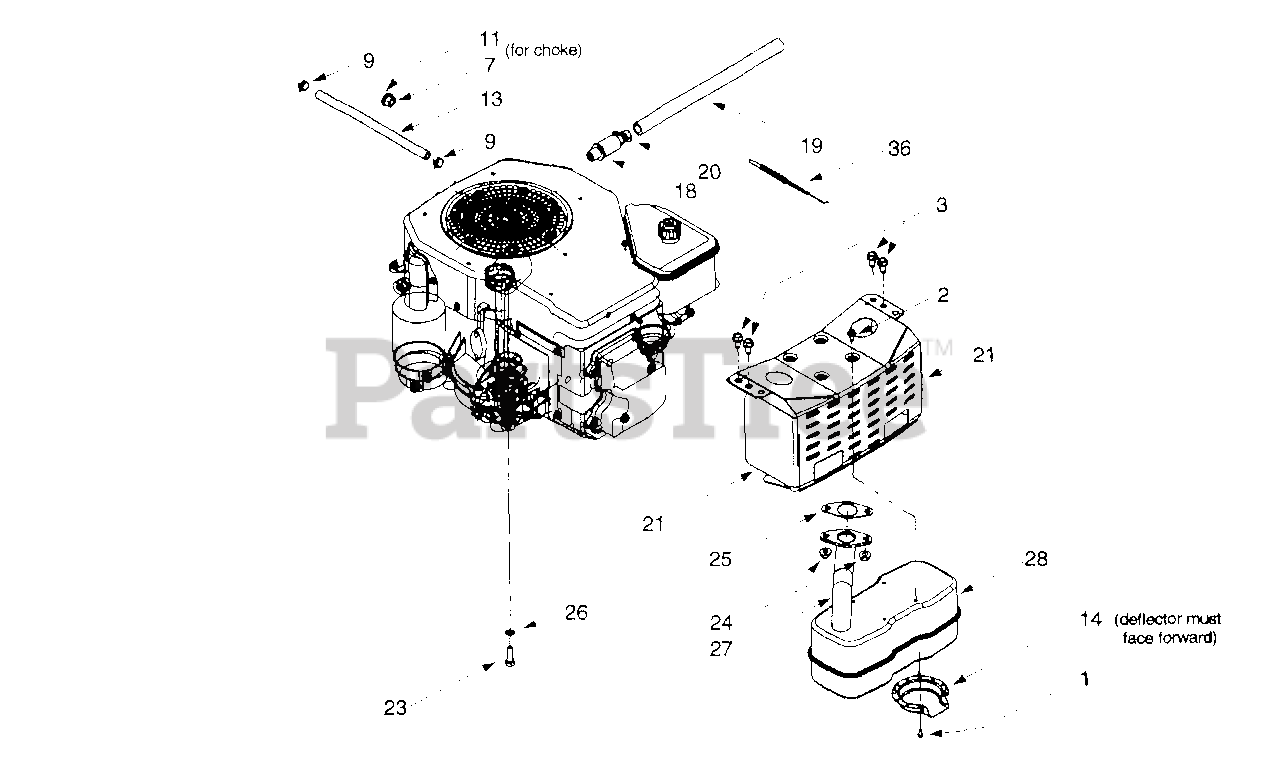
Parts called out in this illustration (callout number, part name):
1	Self Tapping Screw, #8-32 x .375
2	Self Tapping Screw, 1/4-20 x .5
3	Self Tapping Screw, 5/16-18 x .625
7	Hex Nut, 3/8-16
9	Hose Clamp
11	Flat Washer, 3/8 x .56 x .018
13	Fuel Line Hose
14	Muffler Deflector
18	Oil Drain Valve
19	Oil Drain Hose
20	Oil Drain Cap
23	Hex Cap Screw, M8-1.25 x 25
24	Flange Nut, M8-1.25
25	Exhaust Gasket
26	External Lock Washer, 5/16
27	Exhaust Pipe
28	Muffler, Single Inlet
36	Throttle Cable
